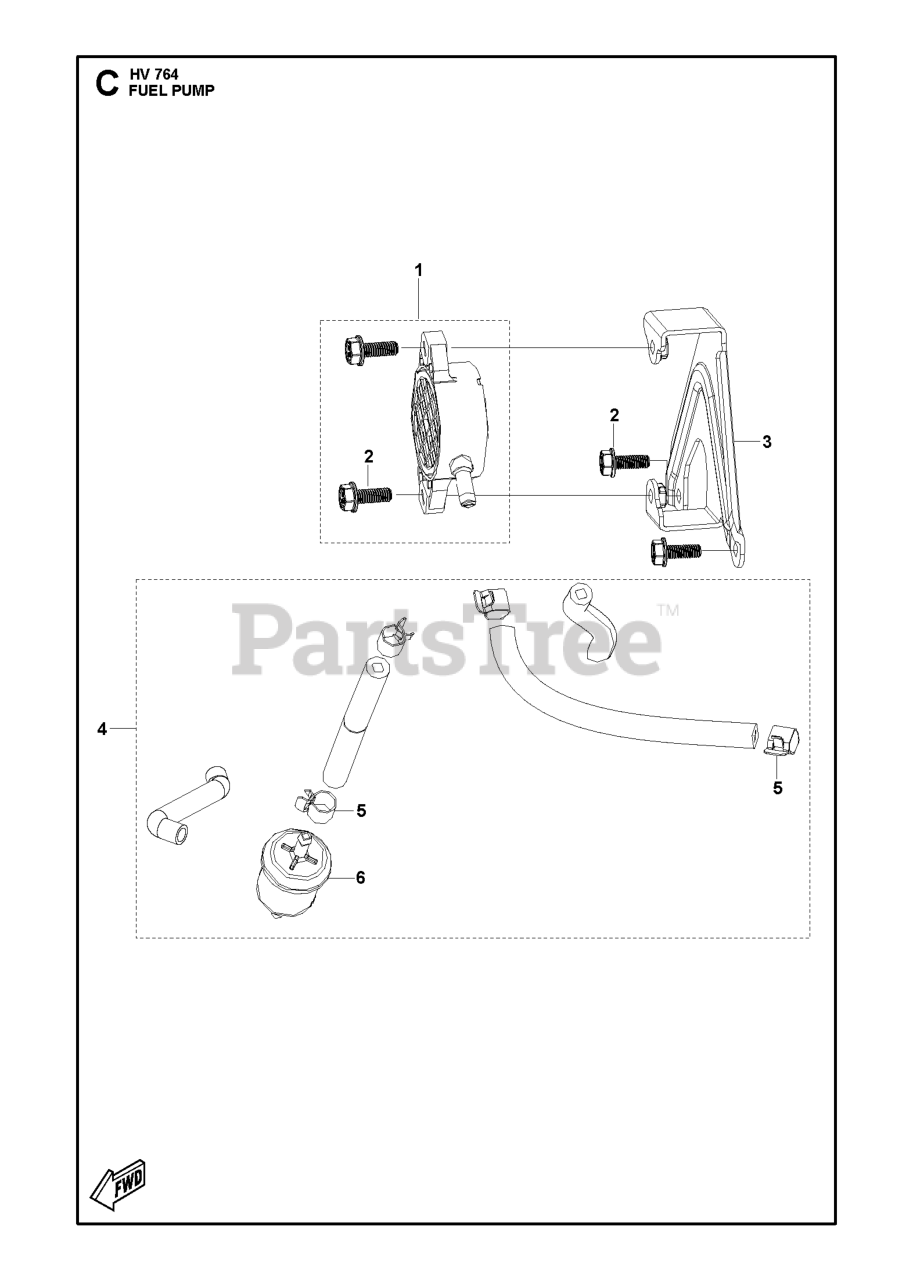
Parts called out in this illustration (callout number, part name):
1	FUEL PUMP FUEL PUMP.
2	Husqvarna TBD
5	CLIP HOSE CLIP
